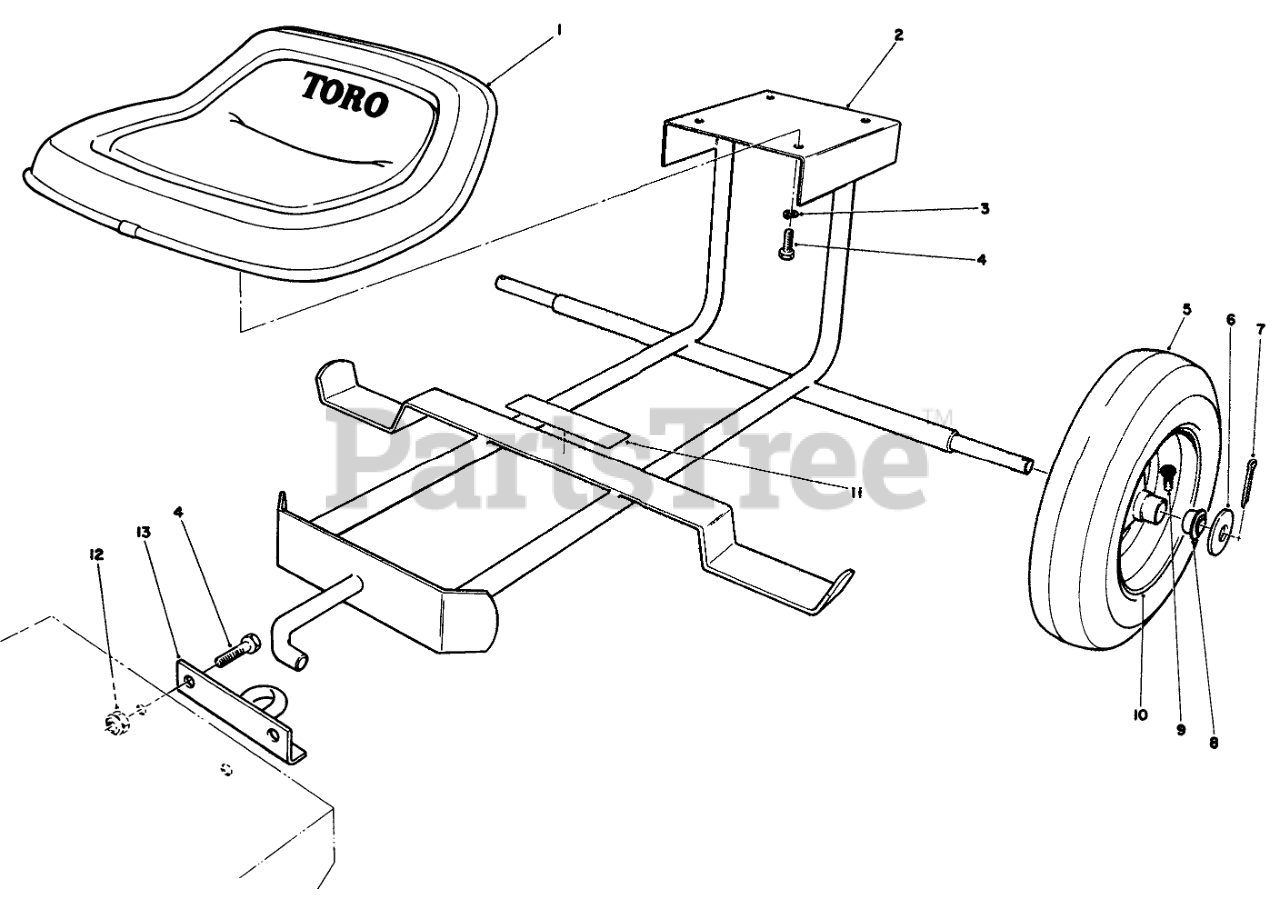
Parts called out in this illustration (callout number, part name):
1	Seat Assembly
2	Frame ASM
3	WASHER-LOCK
4	SCREW-HH
6	WASHER-FLAT
7	PIN-COTTER
8	BEARING
9	VALVE STEM-INNER TUBE
10	WHEEL
11	SULKY DECAL
12	NUT-LOCK, NI
13	HITCH
